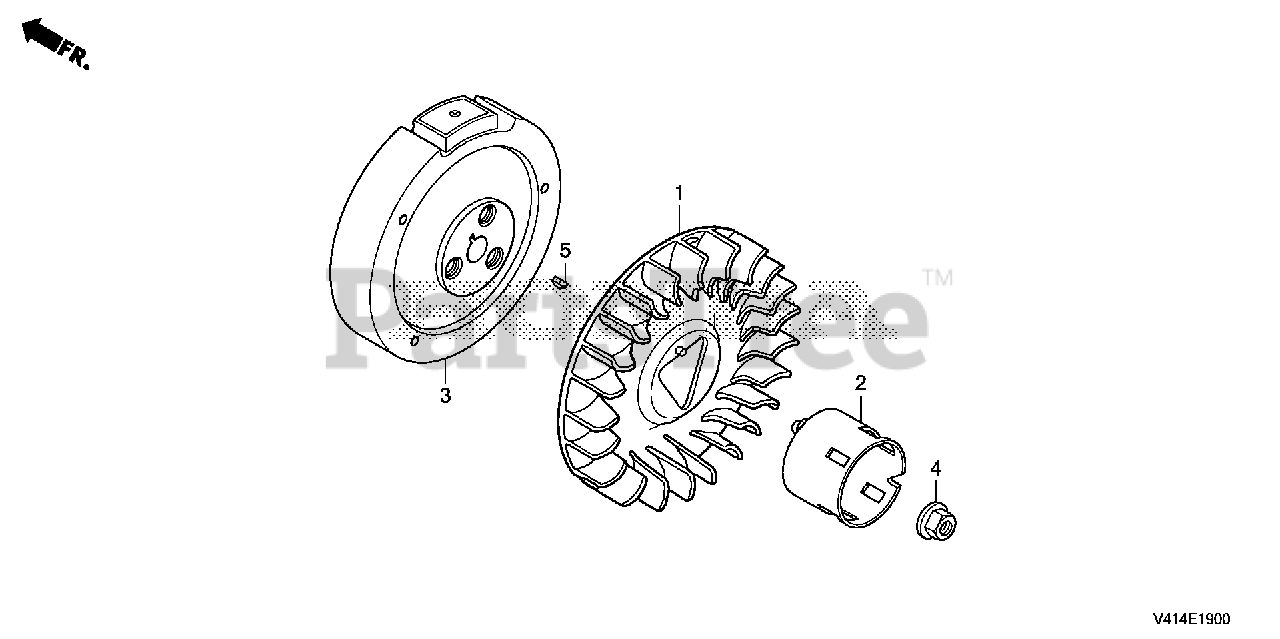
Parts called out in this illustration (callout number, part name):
1	FAN, COOLING
2	PULLEY, STARTER
3	FLYWHEEL (LAMP)
4	NUT, SPECIAL (16MM)
5	KEY, SPECIAL WOODRUFF (25X18)
